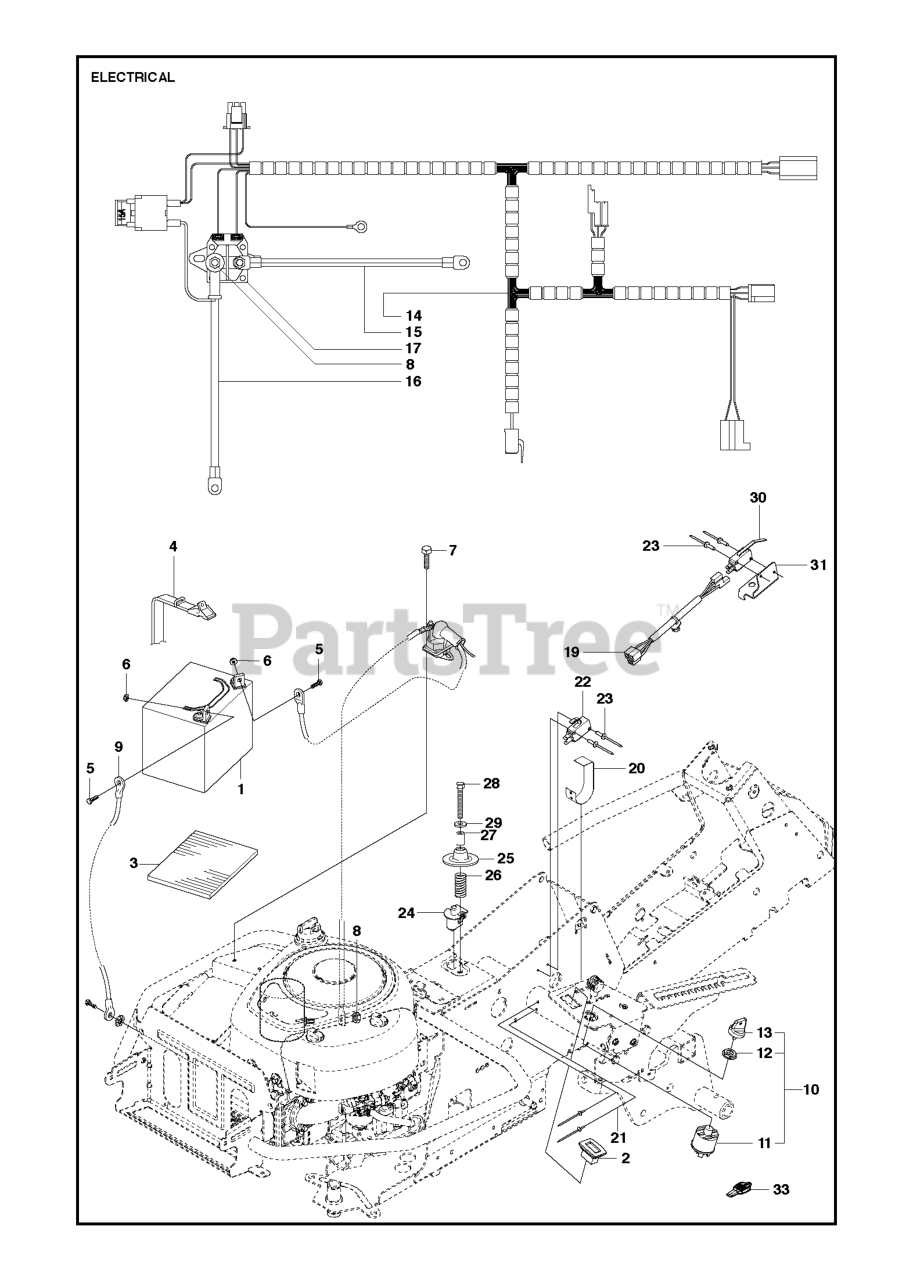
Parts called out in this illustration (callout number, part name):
2	HOUR METER
3	MAT
5	SCREW EHHM
10	IGNITION SWITCH
11	IGNITION SWITCH
13	IGNITION KEY
16	WIRE BATTERY
19	WIRING
20	SPRING
21	Rivet
22	SWITCH
22	MICRO SWITCH
27	SPACER TUBE
28	SCREW
29	WASHER BRB 8.4X17
30	MICRO SWITCH
